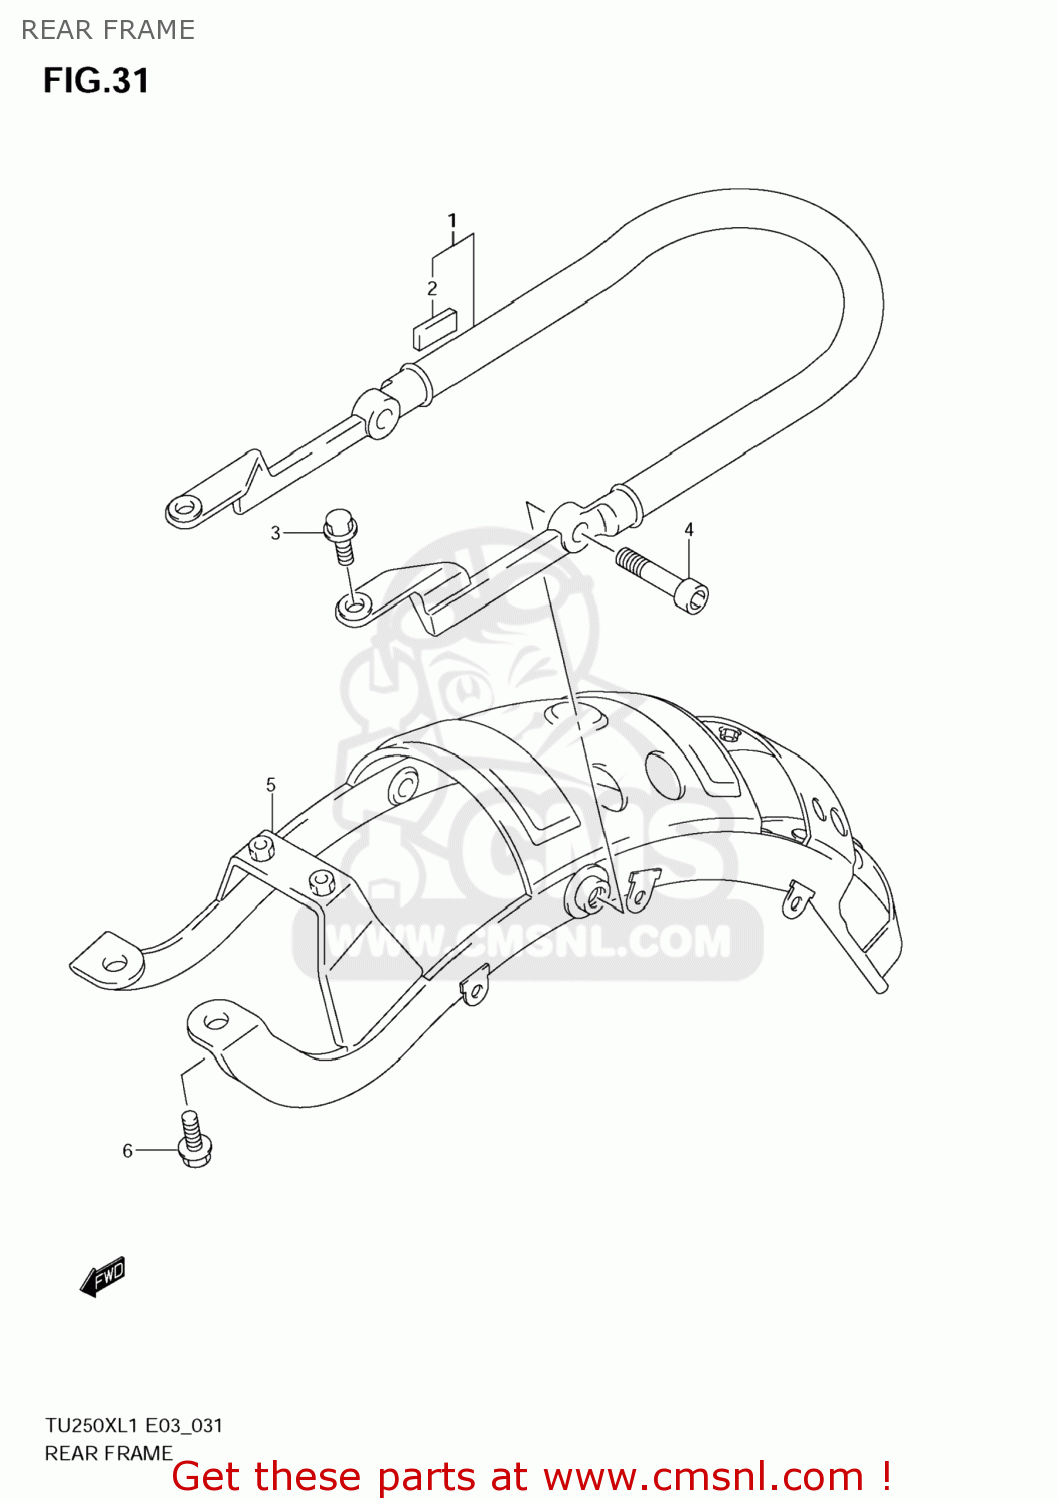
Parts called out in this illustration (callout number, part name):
1	FRAME,RR(BLACK)
2	CUSHION,RR FENDER
3	BOLT(8X25)
4	BOLT(12X45)
5	BRACE,RR FRAME
6	BOLT
